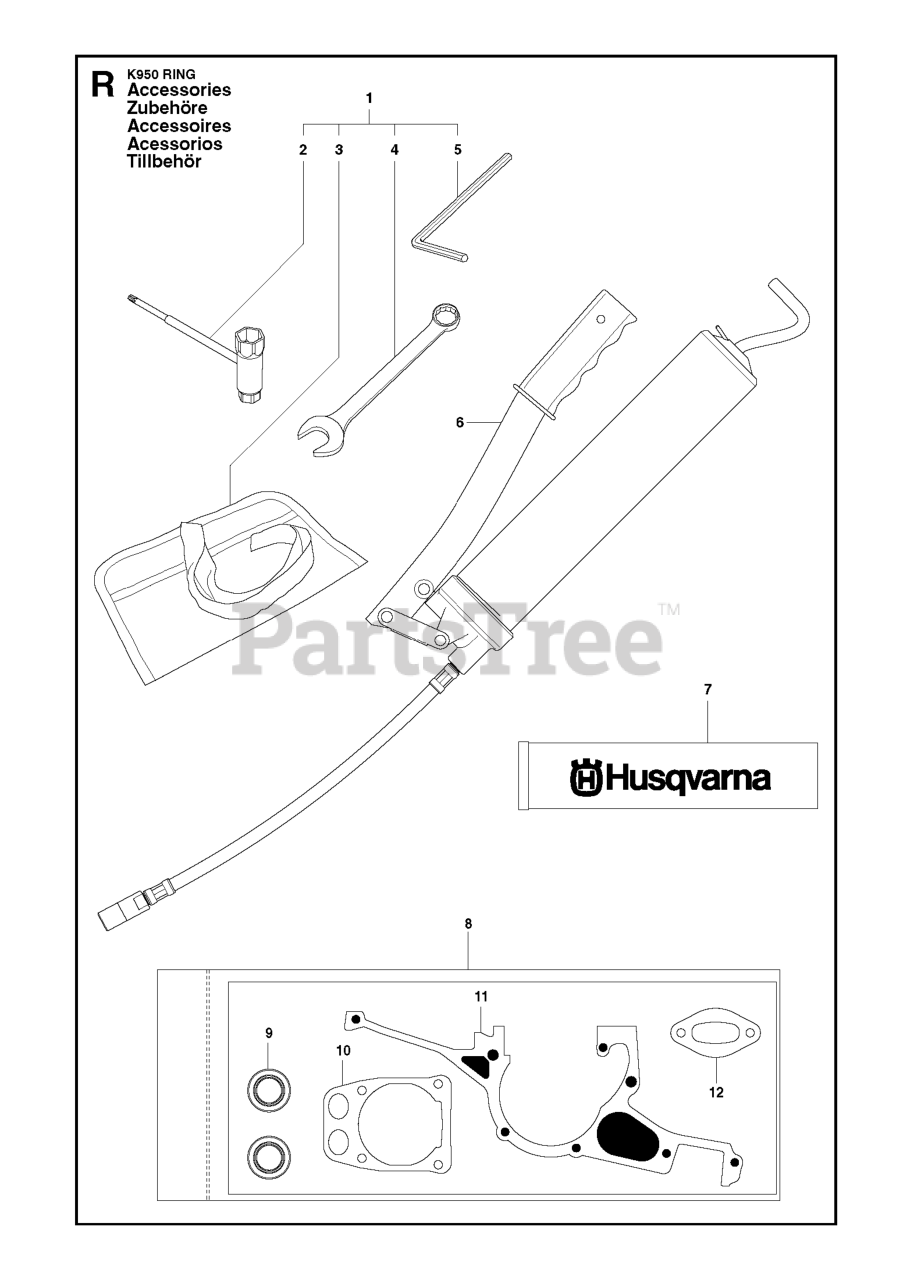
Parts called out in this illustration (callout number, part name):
7	GREASE GUN TUBE SHELL ALVANIA
8	RP GASKET KIT
9	SEALING RING
10	RP GASKET
11	RP GASKET
12	GASKET MUFFLER
